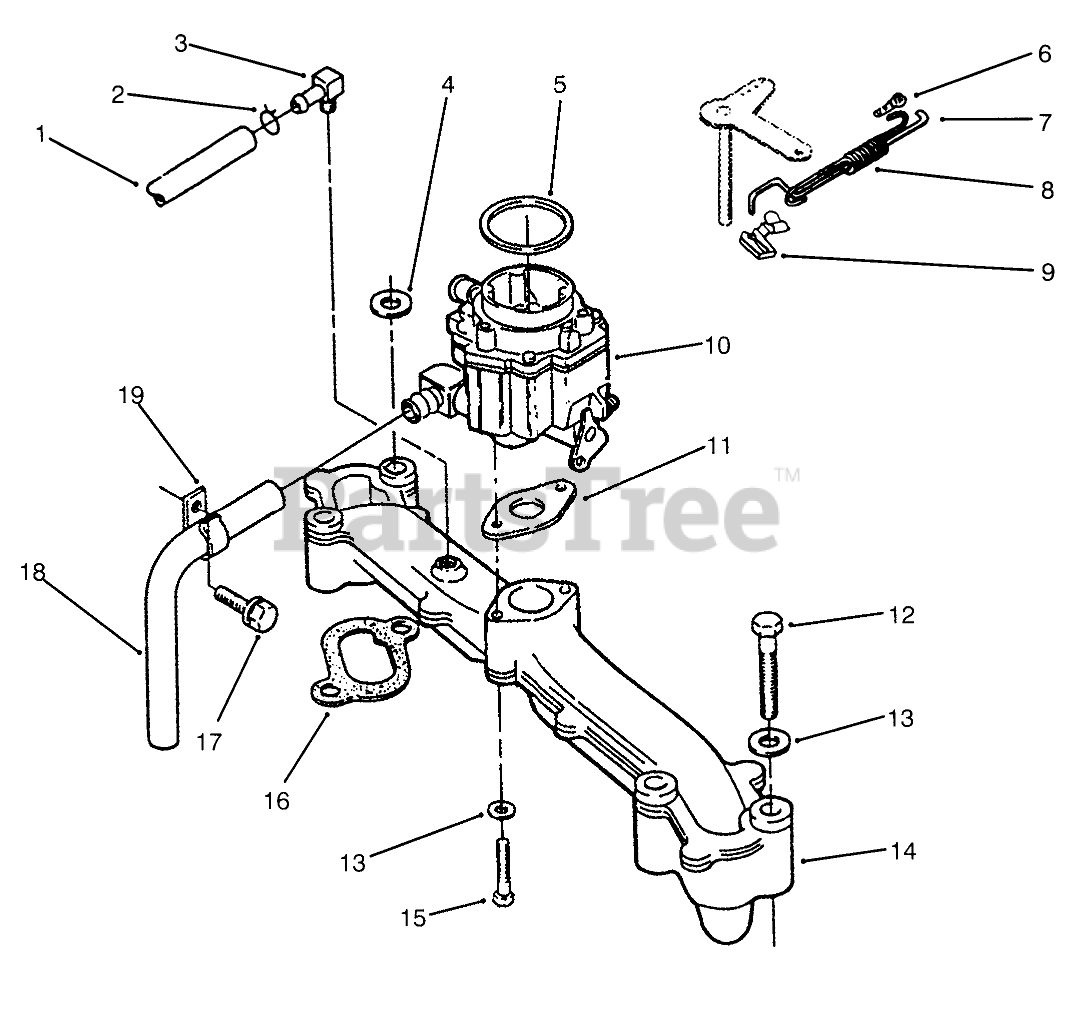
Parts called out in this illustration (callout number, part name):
1	HOSE-RUBBER, BREATHER
2	CLAMP-HOSE
2	CLAMP-HOSE, BREATHER
3	FITTING-BARB
4	FLAT WASHER
7	Governor Control Rod
8	Spring-Governor Rod
10	Assembly-Carburetor (Incl. Ref. #5 & 11)
11	GASKET-CARBURETOR
13	WASHER-FLAT
14	MANIFOLD
15	HEX-HEAD CAP SCREW
16	GASKET
17	SCREW-HWH
18	FUEL HOSE
19	CLIP-WIRE
